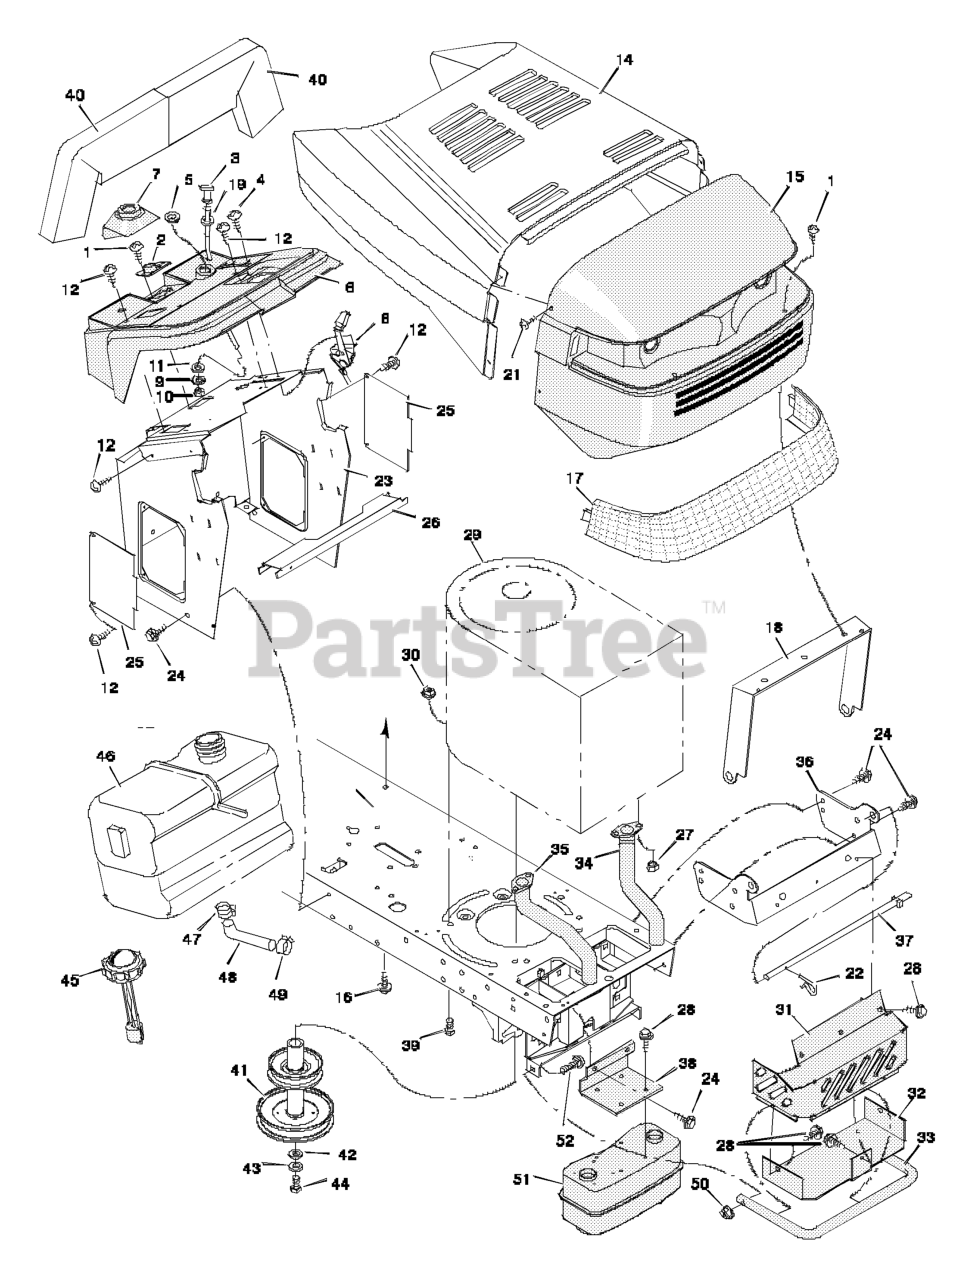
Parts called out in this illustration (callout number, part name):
2	Bearing, Steering Post
3	Cable, Choke
5	Bushing
7	Support, Bellows
8	Throttle Control
9	Lockwasher
10	Nut, Hex
11	Washer
12	Screw
15	Grille
18	Brace, Grille
19	Washer
22	Pin, Hair
23	Console Assembly
25	Panel, Side Access
26	Support, Fuel Tank
27	Nut, Hex
29	Engine *
30	Nut, Flange
31	Shield, Heat
32	Shield, Lower Heat
33	Guard, Muffler
34	Pipe, Left Exhaust
35	Pipe, Right Exhaust
36	Support, Grille
37	Rod, Pivot
38	Bracket, Muffler
39	Bolt, Hex
40	Baffle, Foam
41	Pulley Assembly, Stack
43	Lockwasher
44	Bolt, Hex
45	Cap, Fuel
46	Fuel Tank
47	Clamp, Hose
48	Fuel Line
49	Clamp, Hose
50	Hex, Flange nut
51	Muffler
52	Carriage Bolt
